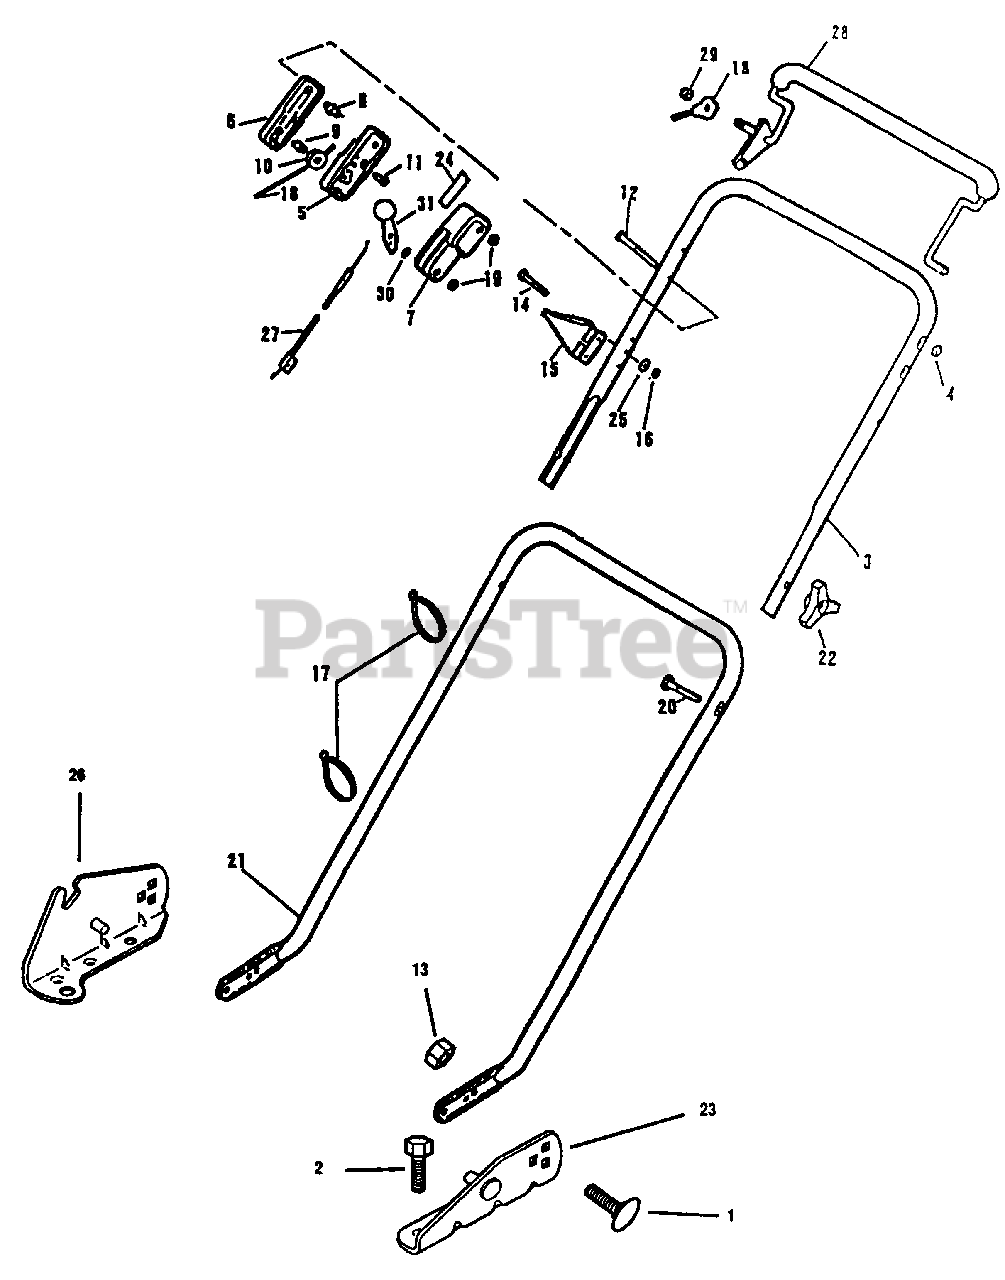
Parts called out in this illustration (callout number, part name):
1	Bolt-Handle Mounting
2	Screw
3	Top Handle
4	Pushnut
5	Control Case-Center
6	Control Case-Outer
7	Control Case-Inner
8	Column
9	Pin
10	Pulley
11	Screw
12	Screw
13	Lock Nut
14	Screw-Truss Head
15	Rope Guide Assembly
16	Locknut
17	Tie Strap
18	Control Cable Assembly
19	Nut-Hex-Centerlock
20	Screw
21	Handle-Bottom
22	Knob
23	Bracket-Handle-L.H.
24	Decal-Throttle
25	Washer
26	Bracket-Handle-R.H.
27	Cable-Throttle
28	Control Lever
29	Nut-Acorn
30	Washer-Spring
31	Lever and Knob Assembly
